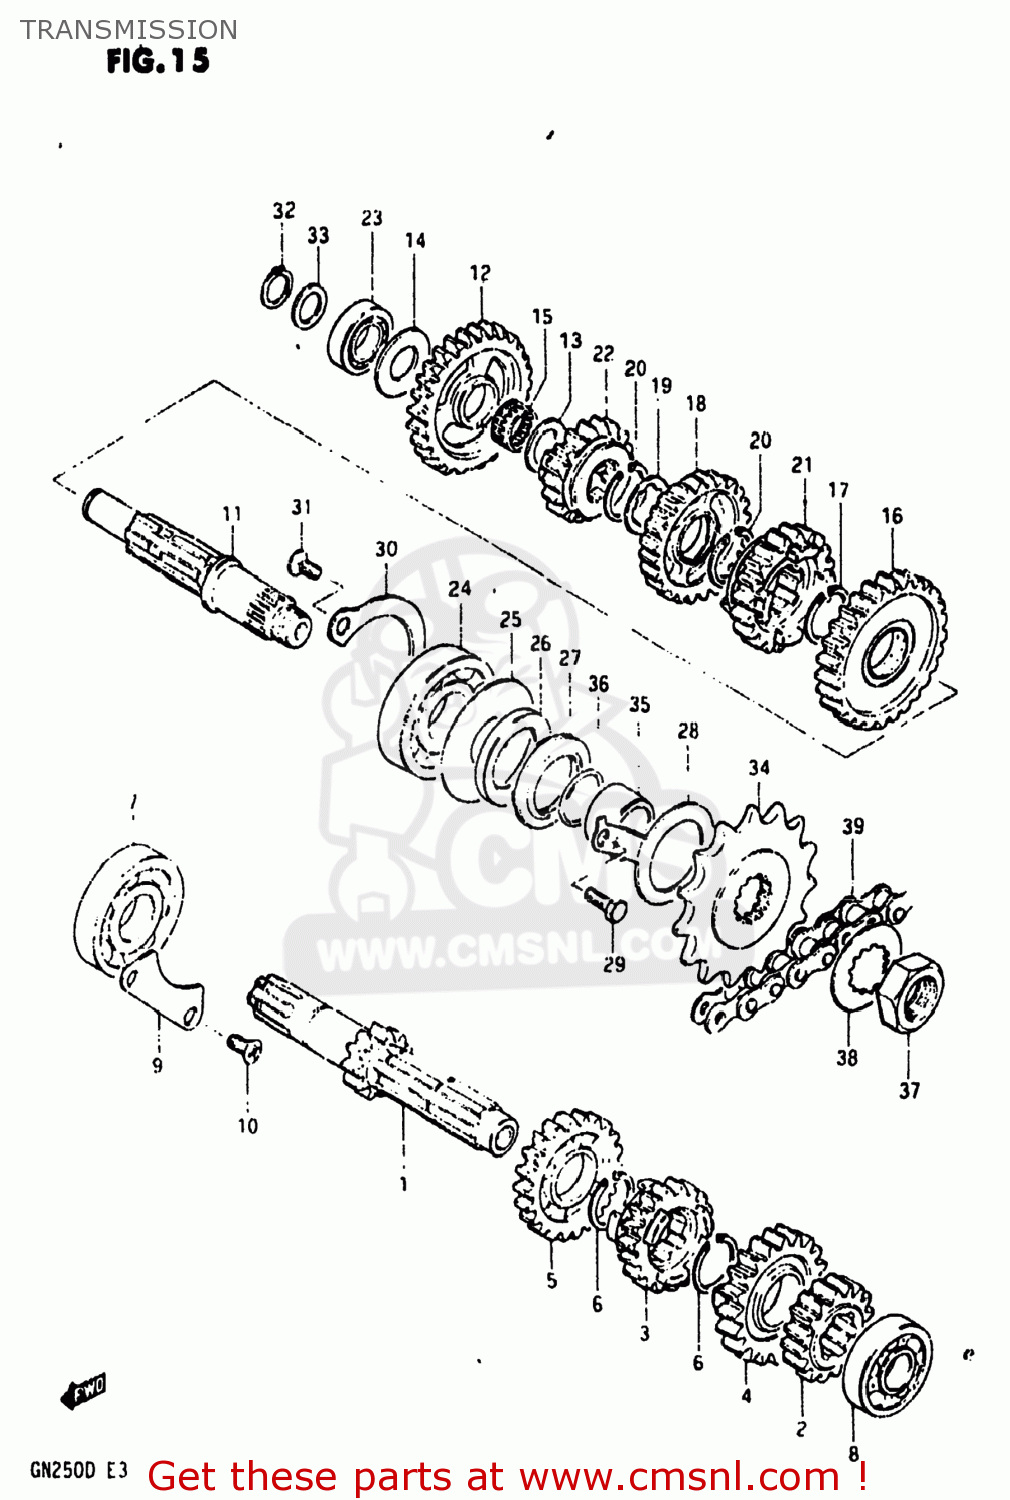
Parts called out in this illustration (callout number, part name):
1	SHAFT,COUNTER
2	GEAR,2ND DRIVE(NT:16)
3	GEAR,THIRD DRIVE (NT:19)
4	GEAR,FOURTH DRIVE
5	GEAR,FIFTH DRIVE
6	CIRCLIP
7	BEARING
8	BEARING
9	RETAINER,CNTR SHAFT BEARING
10	SCREW 6X12
11	SHAFT,DRIVE
12	GEAR,1ST DRIVEN(NT:29)
13	WASHER
14	WASHER
15	BEARING(17X21X9.8)
16	GEAR,2ND DRIVEN(NT:27)
17	CIRCLIP
18	GEAR,THIRD DRIVEN
19	WASHER,LOCK
20	CIRCLIP
21	GEAR,FOURTH DRIVEN
22	GEAR,FIFTH DRIVEN
23	BEARING(17X36X12)
24	BEARING(22X56X16)
25	WASHER(35X55X1)
26	OIL SEAL (30X43X5)
27	OIL SEAL (30X43X7)
28	PLATE,DRIVESHAFT OIL
29	BOLT
30	RETAINER,DRIVE SHAFT BEARING
31	SCREW
32	CIRCLIP
33	WASHER
34	SPROCKET,ENGINE(NT:15)
35	SPACER
36	O RING(D:2.5,ID:21)
37	NUT
38	WASHER,LOCK
39	CHAIN ASSEMBLY,DRIVE
